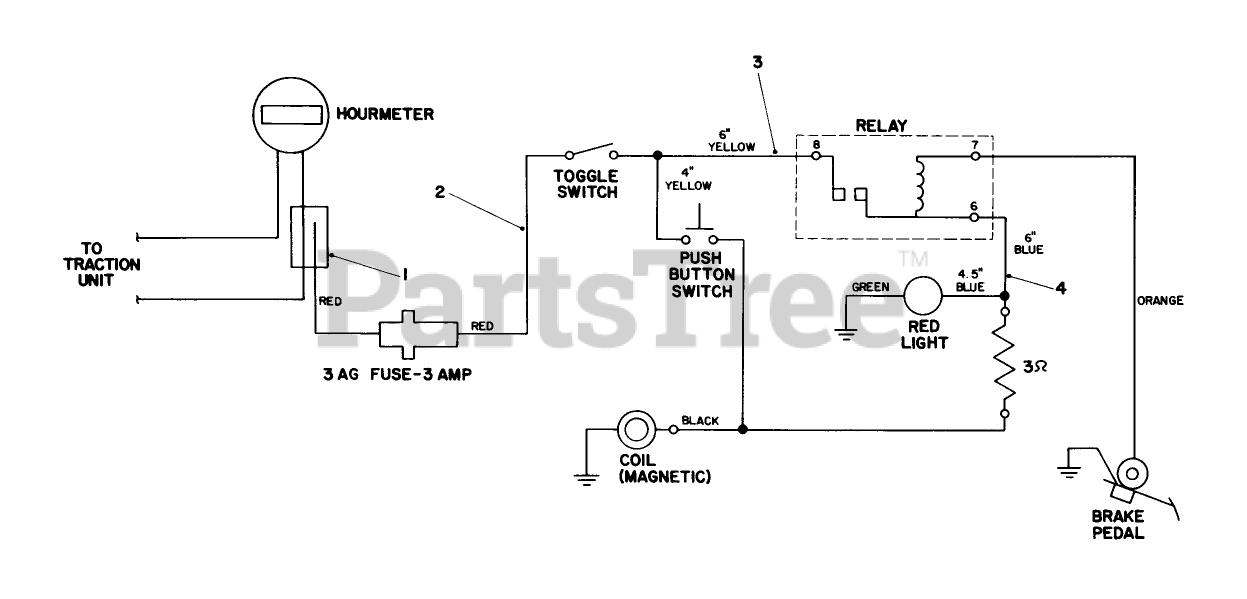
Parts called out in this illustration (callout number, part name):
1	TAP CONNECTOR
2	Wire Harness
3	WIRE ASM
4	WIRE ASM
